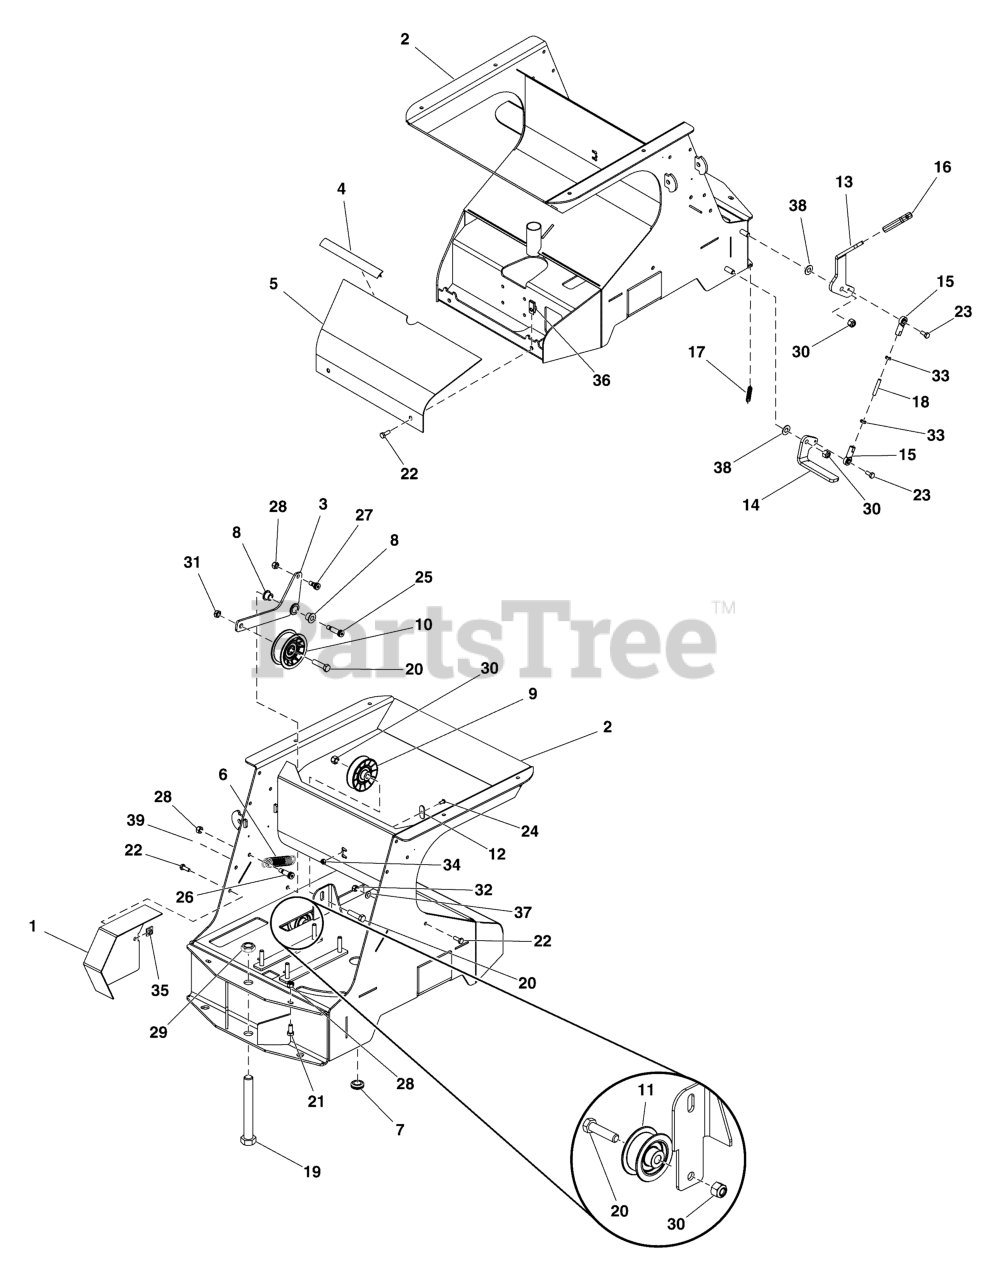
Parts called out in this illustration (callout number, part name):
1	WELD, PULLEY GUARD, ROVER
2	WELD, FRAME ROVER
3	WELD, ARM IDLER ROVER
4	SEAL TRIM, FRONT COWL 7" LONG
5	FRONT COWL, ROVER (SANDED)
6	SPRING, EXTENSION .840" OD X 4.00" LONG SS
7	GROMMET 1.00" I.D. FIT 1.38"HOLE
8	BSHG-FL, .500" X .625" X .500", .875"x .062" IR
9	PULLEY V-BELT IDLER 1.79" OD X 3/8" BORE
10	PULLEY IDLER 2.75" OD X 3/8" BORE
11	PULLEY IDLER 1.75" OD X 3/8" BORE
12	PLATE, CABLE HOLDER
13	HANDLE, PARK BRAKE
14	BRACKET, BRAKE BAR
15	ROD END, FEMALE 1/4-28 RH SS PTFE RACE
16	GRIP, .188" X 1.00" ID X .150" THK CLSD CELL FOAM
17	SPRING, EXTENSION .375" OD X 2.500 LONG SS
18	ROD, THREADED .250"-28 X 1.500" SS188
19	SCR-CAP, HEX .750"-10 X 6.000" SS188
20	SCR-CAP, HEX .375"-16 X 1.500" SS188
21	SCR-CAP, HEX .3125"-18 X .750" SS188
22	SCR-CAP, HEX .250"-20 X .750" SS188
23	SCR-CAP, HEX .250"-20 X .625" SS188
24	SCR-CAP, BSH #10-24 X .500" SS188
25	BLT-SLDR,SH.50"X1.25",.375"-16X.63"SS188
26	BLT-SLDR, SH .38"X0.75,.313-18 X.50 SS
27	BLT-SLDR, SH .375" X 0.250", .3125"-18 X.500" SS188
28	NUT-HEX-NYLK, 0.3125"-18 SS188
29	NUT-HEX-NYLK, .750"-10 TH GA ZP
30	NUT-HEX-NYLK, .375"-16 SS188
31	NUT-HEX-NYLK, .375"-16 TH SS188
32	NUT-HEX-NYLK, .250"-20 SS188
33	NUT-HEX, JAM .250"-28 SS188
34	NUT-HEX-NYLK, #10-24 SS188
35	NUT-CLIP, .250"-20 X .375" EDGE DISTANCE
36	NUT-CLIP .250"-20 X .781" EDGE DISTANCE
37	WSHR-STL, FLT .281" X .625" X .050" IS SS188
38	WSHR-STL, FLT .406" X .875" X .050" IS SS188
39	NUT-HEX-NYLK, FLG .375"-16 SS188
